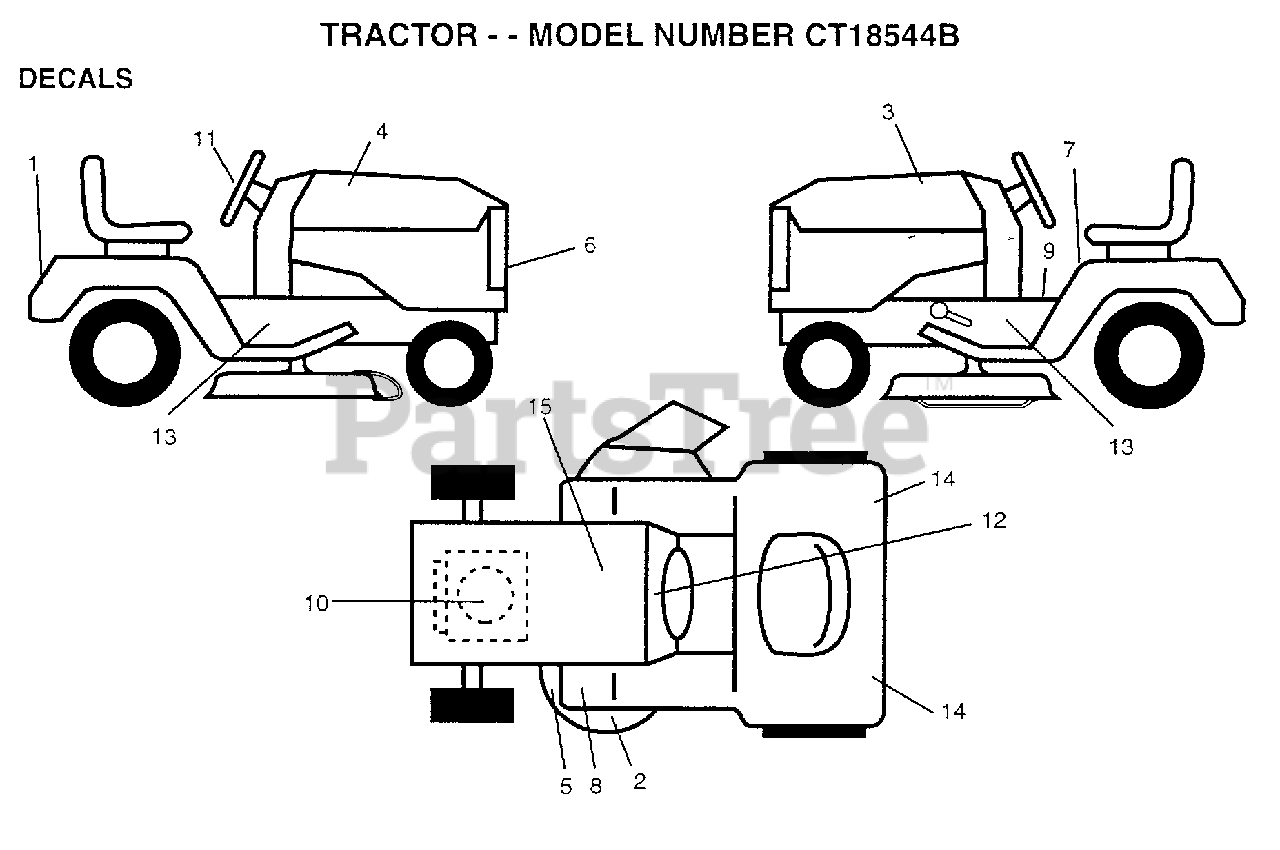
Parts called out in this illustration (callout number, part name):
1	DECAL.FEND.RALLY
3	DECAL HOOD LH
4	"DECAL,HOOD RH"
5	"DECAL.V.BELT.44"""
6	DECAL.GRILLE.RLY
7	DECAL
9	DECAL BRAK PARK
10	DECAL, HP, ENGINE
11	DECAL.WHL.STR.RLY
12	DECAL.DASH.INST.
13	DECAL CHASSIS 6SP
14	REFLECTOR-TAIL YT
15	DECAL.BTRY.DANGER
